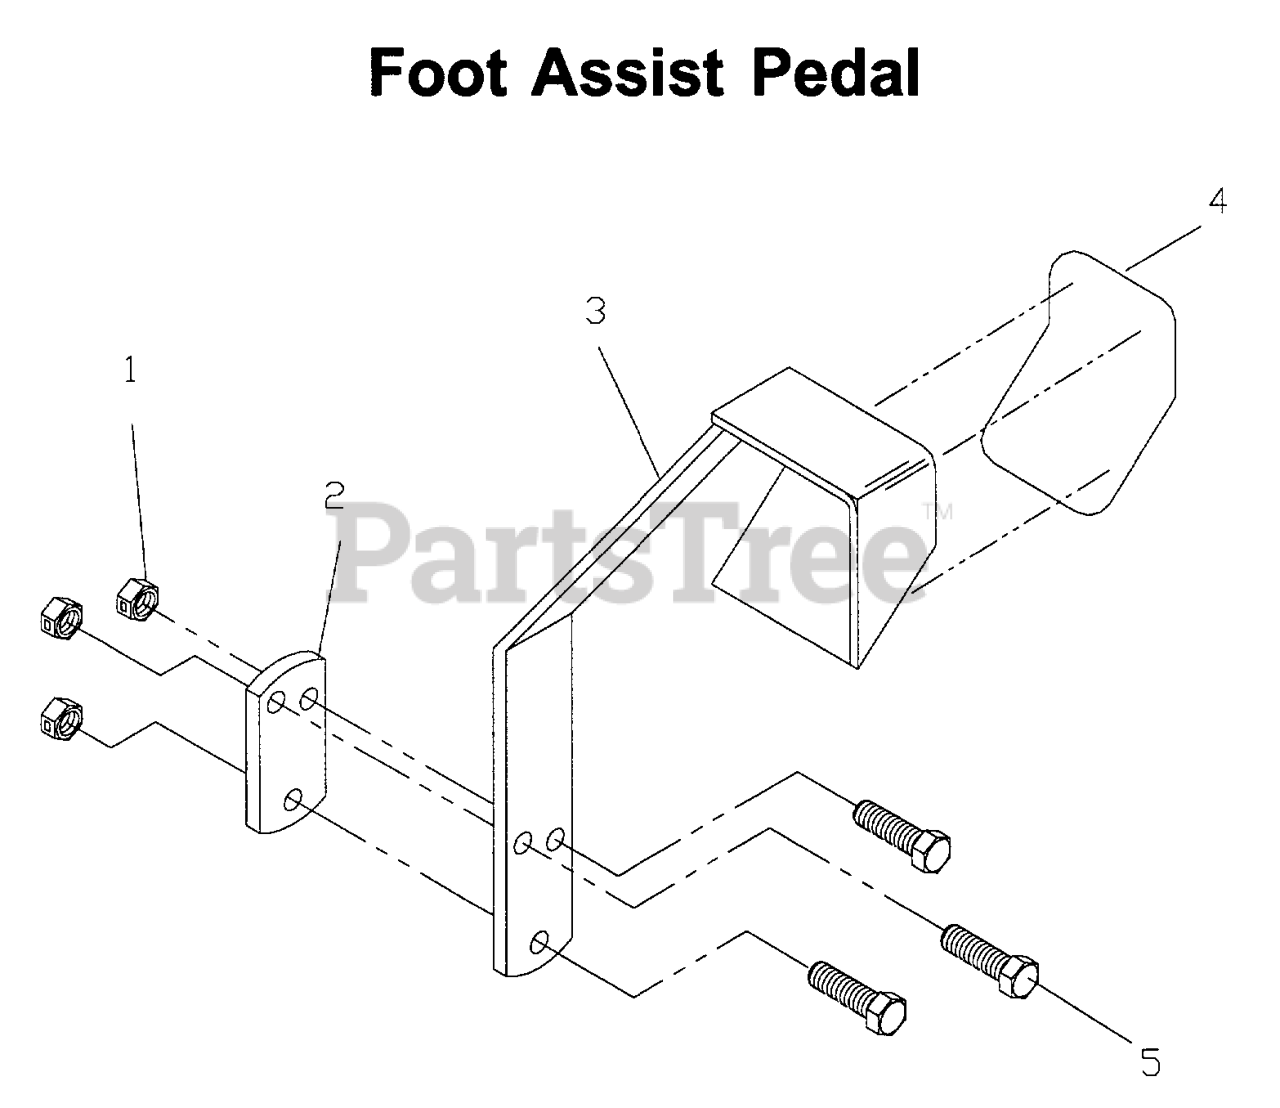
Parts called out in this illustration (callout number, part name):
1	NUT 3/8-16 NYLOC
2	TIGHTENING PLATE BLK
3	LIFT PEDAL BLK
4	ANTI-SKID PAD
5	HCS 3/8C X 1 1/2
